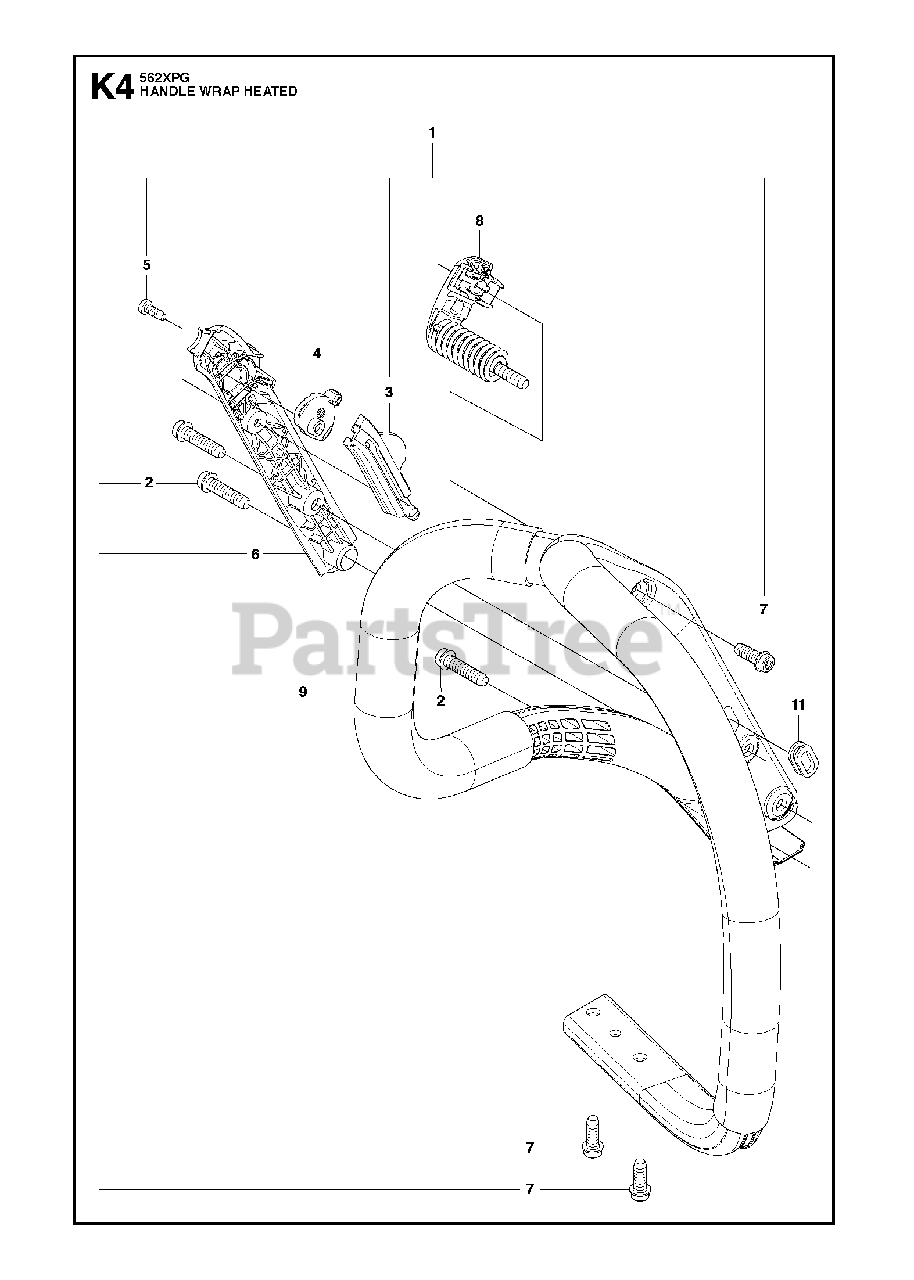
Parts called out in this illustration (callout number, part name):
1	FRONT HANDLE
2	SCREW
3	COVER
4	HANDLE
5	CONTACT PLATE
6	SCREW
7	SCREW IHSCFT
8	ANTIVIBRATION ELEMENT
9	HANDLE WRAP W
